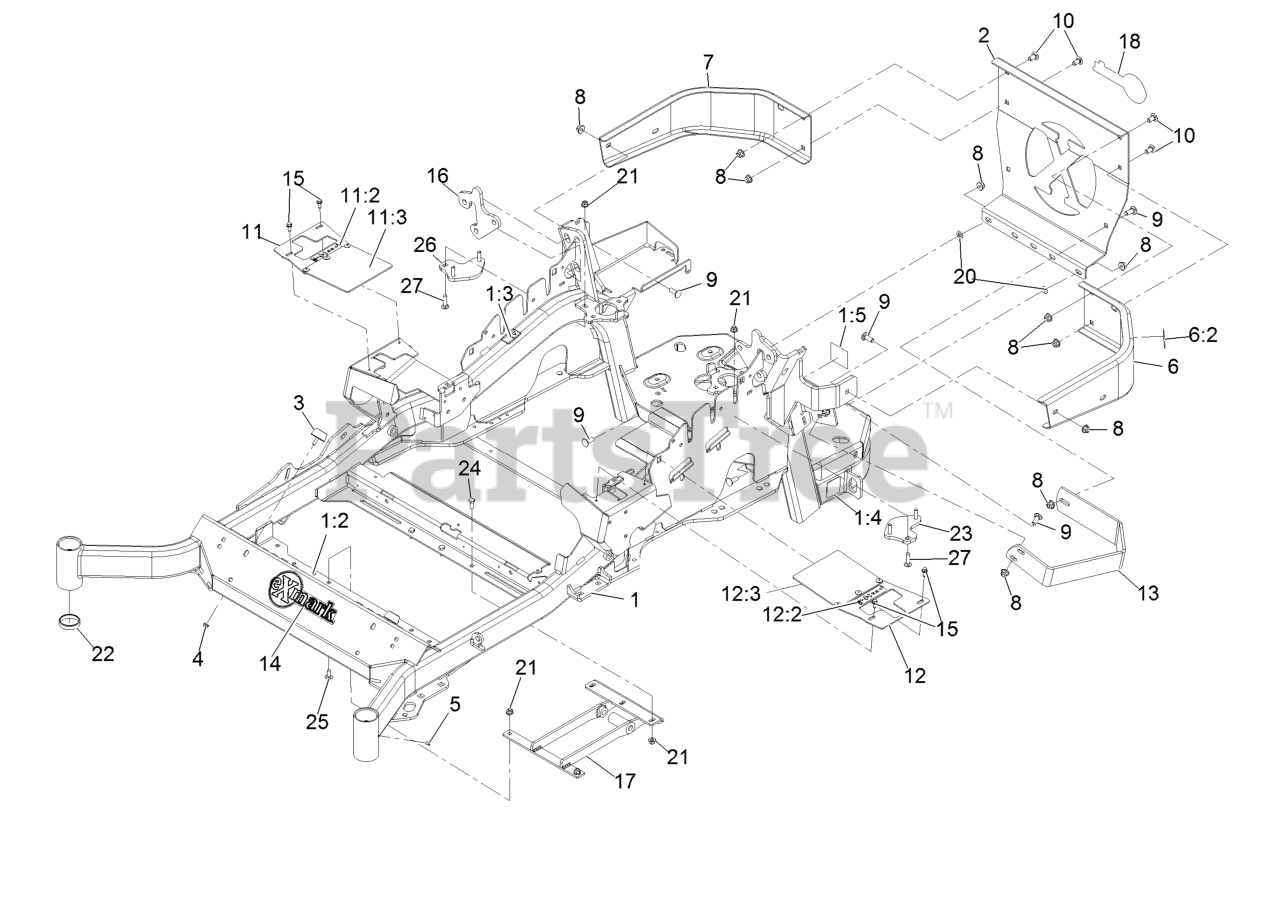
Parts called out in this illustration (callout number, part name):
1	Mainframe ASM
1:2	Decal-Danger
1:3	Decal-Warning
1:4	Decal-Hazard, Pinched Finger
1:5	Decal-Spark Arrester
2	Plate,Rear Guard
4	Nut-Nyloc 1/4-20 Flg
6	LH Bumper ASM
6:2	Decal-Warning
7	Bumper-RH
8	Nut-Nyloc 3/8-16 Flg
9	Bolt-Carriage 3/8-16 X 1
10	Bolt-Carriage 3/8-16 X 3/4
11	RH Motion Control Cover ASM
11:2	Decal-Control, Motion
11:3	Flap-Rubber
12	LH Motion Control Cover ASM
12:2	Decal-Control, Motion
12:3	Flap-Rubber
13	Guard-Muffler
14	Decal-Exmark
15	Screw-HWH 1/4-20 X .62
16	Plate-Mount, Shock
17	Mount-Lower
18	Decal-Exmark Logo
20	Nut-Push 3/8-16
21	Nut-Nyloc 5/16-18 Flg
22	Cup-Bearing Tapered Roller
23	LH Plate ASM (W/Studs)
24	Screw-HH 5/16-18 X 3/4
25	Bolt-Carriage 5/16-18 X 3/4 Short Neck
26	RH Plate ASM (W/Studs)
27	Bolt-Carriage 5/16-18 X 1 1/4
